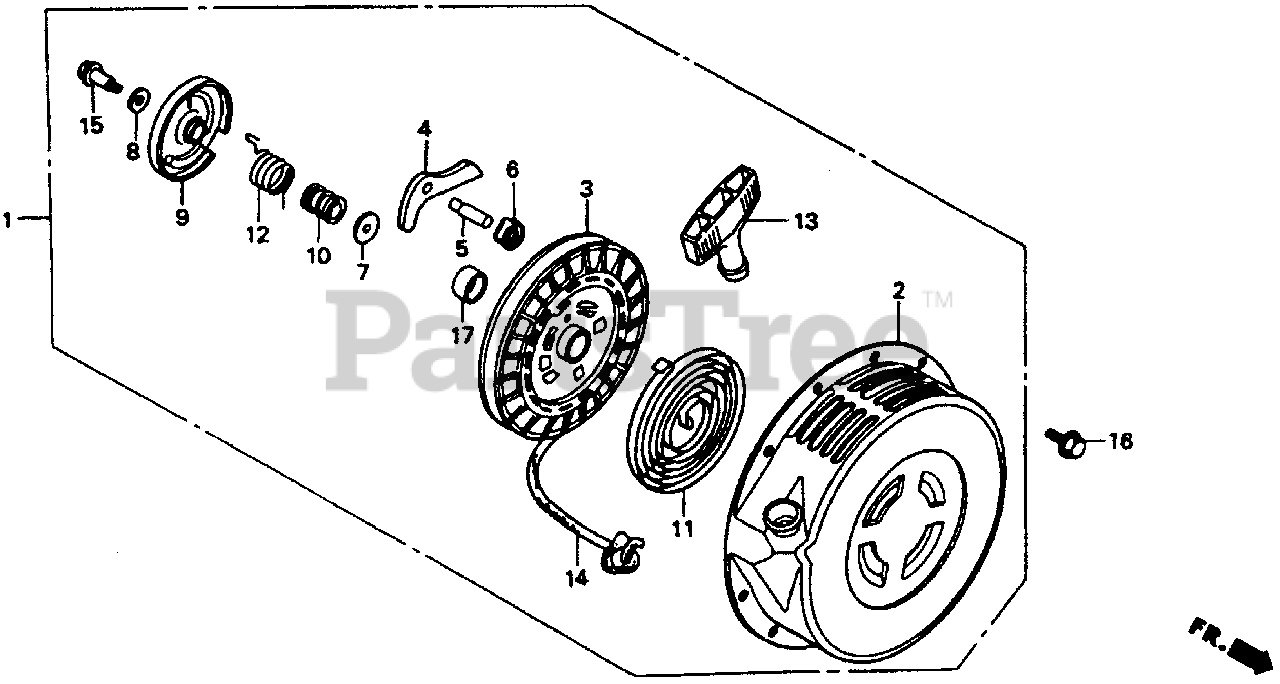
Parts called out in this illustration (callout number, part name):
1	STARTER ASSY., RECOIL
2	CASE, STARTER
3	REEL, STARTER
4	RATCHET, STARTER
5	SHAFT, RATCHET
6	PLATE, GUIDE
7	PLATE A, FRICTION
8	PLATE B, FRICTION
9	COVER, REEL STARTER
10	SPRING, FRICTION
11	SPRING, RETURN
12	SPRING, TORSION
13	GRIP, STARTER
14	ROPE, STARTER (#6X64")
15	BOLT, REEL COVER
16	BOLT, FLANGE (6X8)
17	COLLAR
